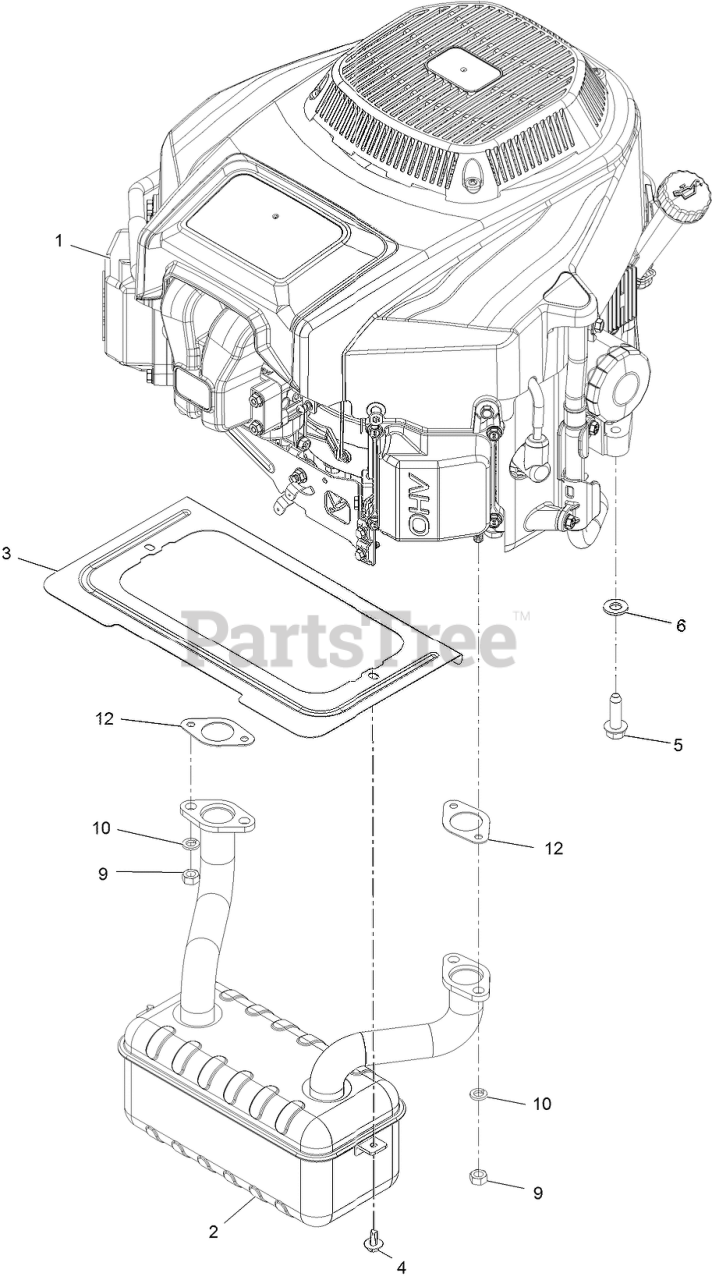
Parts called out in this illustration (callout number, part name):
2	MUFFLER
3	SHIELD-HEAT
4	SCREW-HHFTF
5	SCREW-THD
6	WASHER-FLAT
9	NUT-HH
10	WASHER-LOCK, SPLIT
12	GASKET-EXHAUST
